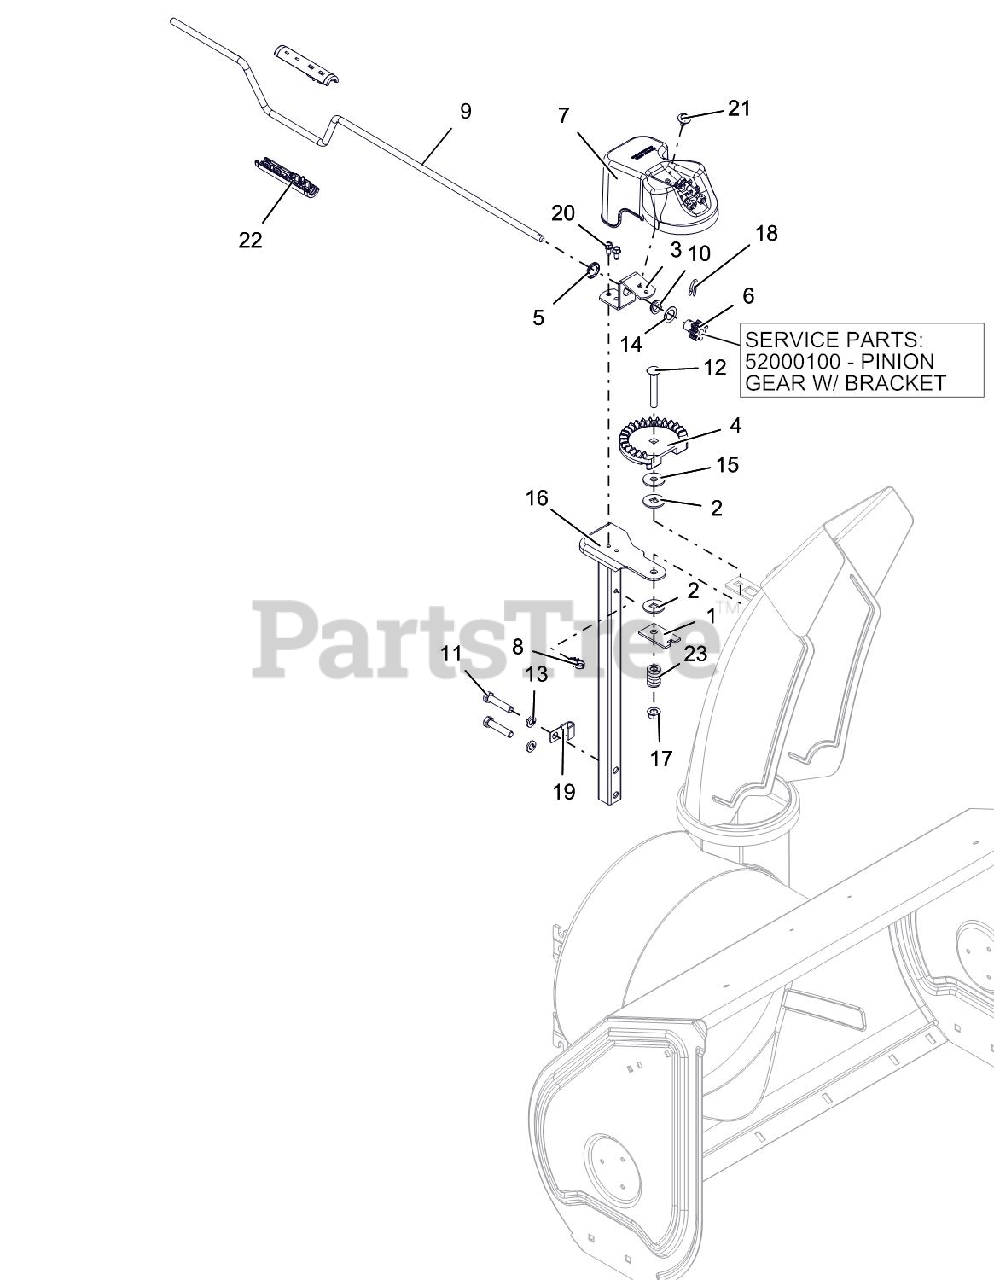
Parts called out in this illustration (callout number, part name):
1	PLATE, FRICTION
2	FRICTION WASHER
3	BRACKET, PINION GEAR
4	CHUTE GEAR
5	PUSHNUT .625
6	PINION GEAR W/BRACKET
6	PINION GEAR - CHUTE
7	GEAR COVER ASSY LG SHEAR BOLT
8	CLIP, CABLE GUIDE
9	ROD,CRANK - LGDASH DLX
10	BUSHING, POLYLINER-.63 SNAPIN
11	@BLT-HEX .38-16X1.75 GR5 YWZC
12	@BLT-RDHDSQNK .38-16X2.50 G5YZ
13	@WSHR-LK .38X.094 REG YWZC
14	WSHR-THRST .625 X 1.0 X .03
15	@WSHR-FL-STL .406X1.25X.10 ZC
16	PEDESTAL, CHUTE - CRANK
17	@NUT-LK-TOP-FLG .38-16 YWZC
18	PIN, SPRING CLIP
19	J-CLAMP
20	SCR-TAP .25-20X.50 HWH TR YWZ
21	SCR-TAP .25-20X.50 LGHWH TR YZ
22	KNOB,CHUTE CRANK-DELUXE
23	SG-COMP .187X.56X1.62
